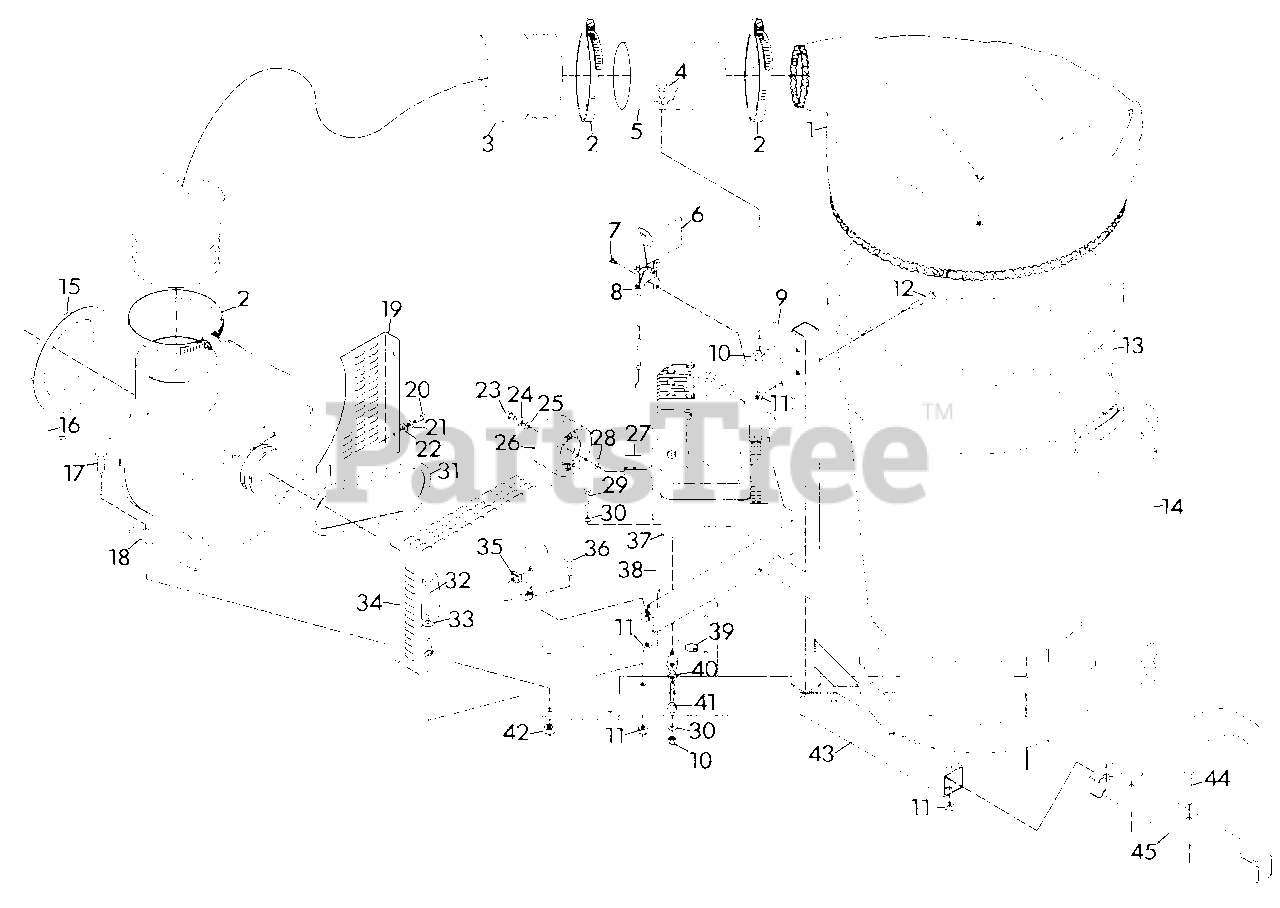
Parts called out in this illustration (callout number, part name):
1	COVER, TOP
2	CLAMP
3	HOSE, BLOWER TO CAN
4	BOLT, HEX 5/16-18X.625
5	TUBE, CONNECTOR
6	DECAL, THROTTLE
7	SCREW, TAPPING 10-24X.50
8	LEVER, THROTTLE CONTROL
9	BRACKET, TUBE
10	NUT, LOCK 5/16-18
11	NUT, LOCK 3/8-16
12	BOLT, HEX 3/8-16X2.25
13	CAN, GRASS
14	STRAP, HOLD DOWN
15	ADAPTER, HOSE
16	HANDLE, LOCKING
17	BOLT, HEX 1/2-13X1.25
19	COVER, GUARD
20	BOLT, HEX 1/4-20X.75
21	WASHER, LOCK 1/4 REG.
22	WASHER, FLAT .281X.625X.065
23	BOLT, HEX 5/16-24X.75
24	WASHER, LOCK 5/16 REG.
25	WASHER, FLAT .313X.875X.065
26	CLUTCH
27	KEY, HUB .187X1.500
28	RACE, BEARING THRUST .060
29	BOLT, HEX 5/16-18X1.75
30	WASHER, FLAT .344X.688X.065
31	V-BELT
32	BOLT, HEX 3/8-16X2.75
33	WASHER, FLAT .406X.812X.065
34	GUARD
35	NUT, RETAINER
36	BOLT, HEX 3/8-16X.875
38	PIN, CLEVIS 3/8X2.62
39	PIN, KLIK
40	NUT, HEX 3/8-16
41	BOLT, HEX SPEC. 3/8-16X3.00
42	NUT, LOCK 1/2-13
43	WELDMENT, FRAME
44	BOLT, HEX 3/8-16X2.50
45	WELDMENT, HANGER TUBE
